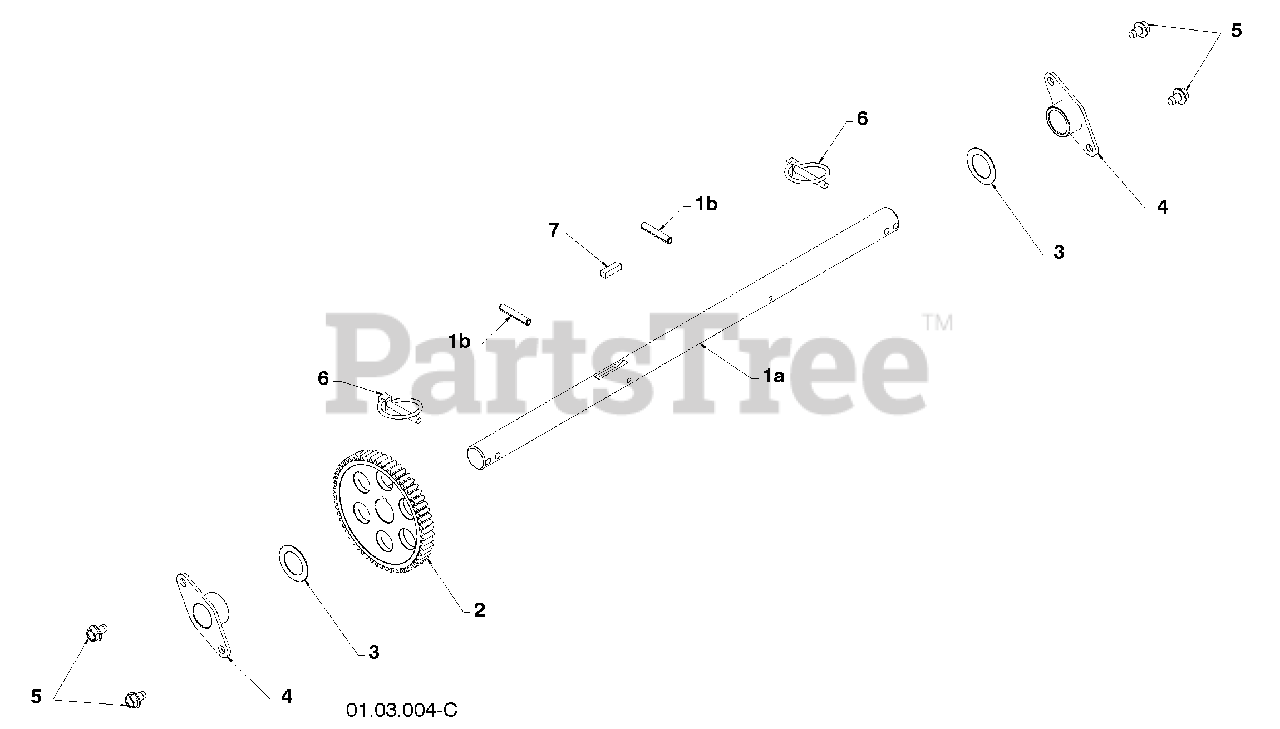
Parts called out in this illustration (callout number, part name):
1	(assy of 1a,1b) AXLE ASSEMBLY
2	GEAR
3	THRUST WASHER
5	BOLT 5/16-18 X .500
7	SQUARE KEY
